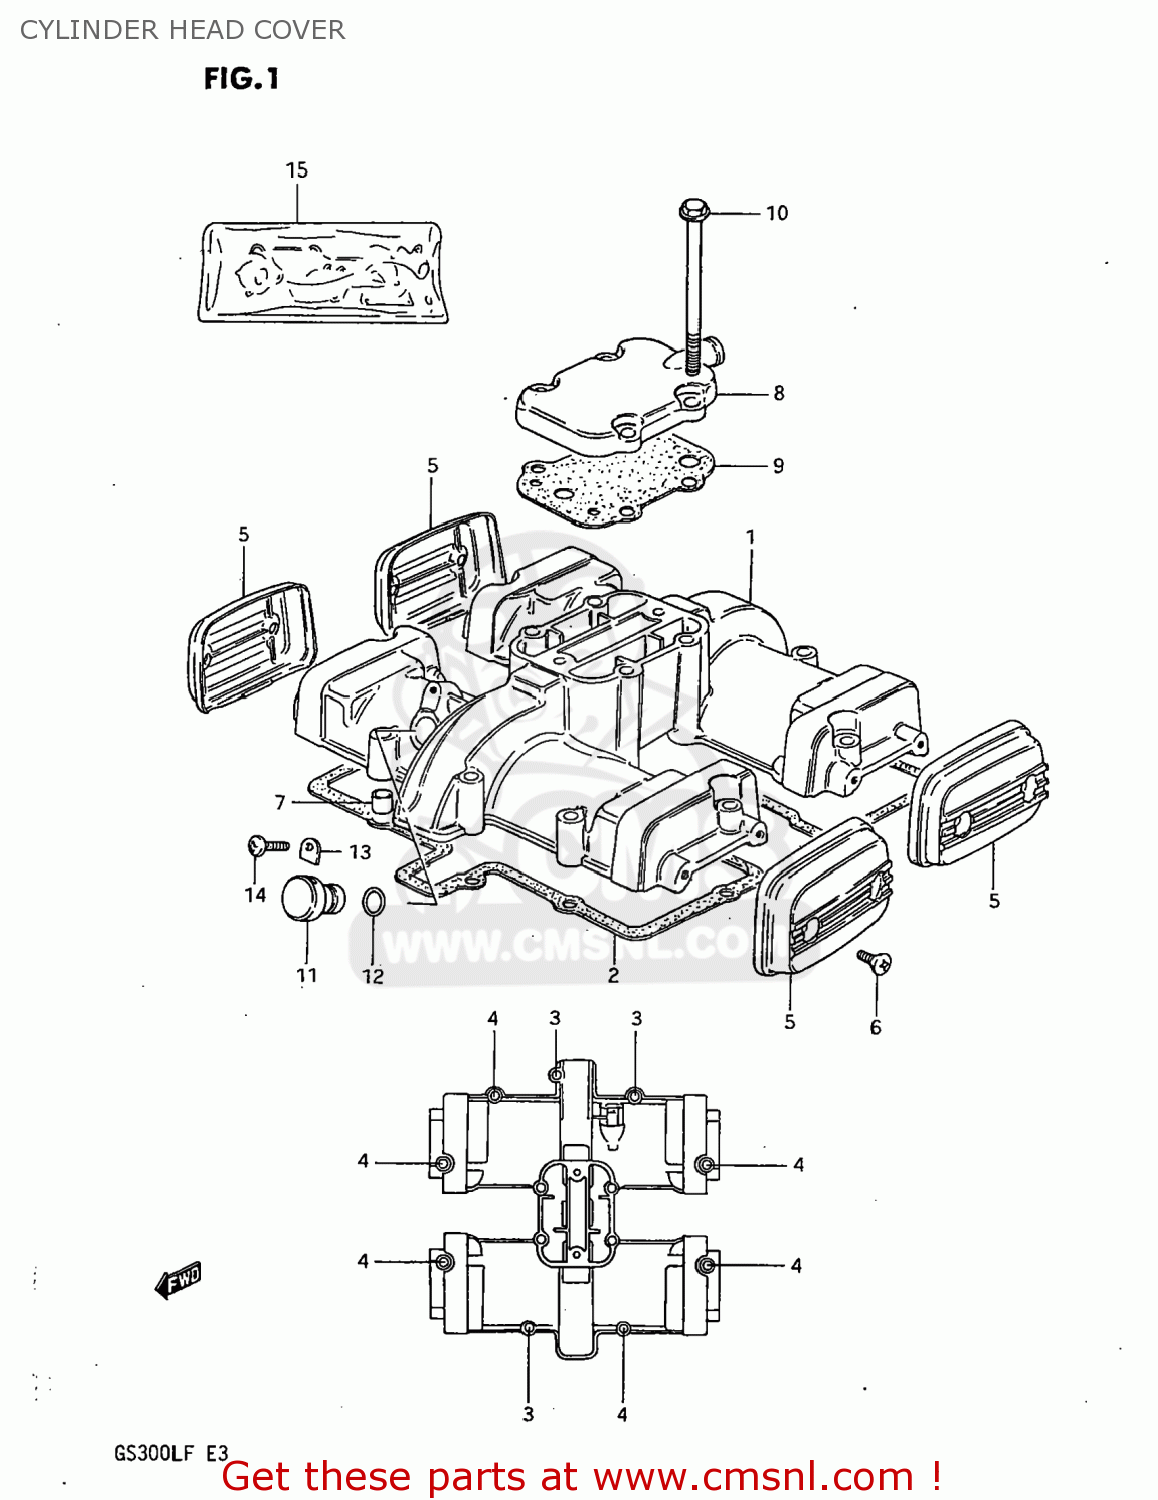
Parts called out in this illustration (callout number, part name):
1	COVER,CYLINDER HEAD
2	GASKET,CYLINDER HEAD COVER (MCA)
3	BOLT
4	BOLT 6X35
5	CAP,CYLINDER HEAD COVER
6	SCREW(5X12)
7	PIN(6.2X8X11)
8	COVER,BREATHER
9	GASKET,BREATHER COVER (MCA)
10	BOLT (6X75)
11	PLUG,TACH GEAR SLEEVE HOLE
12	SEAL,TACHOMETER DRIVEN
13	PLATE,TACH DRIVE GEAR SLEEVE
14	SCREW(5X12)
15	GASKET SET
